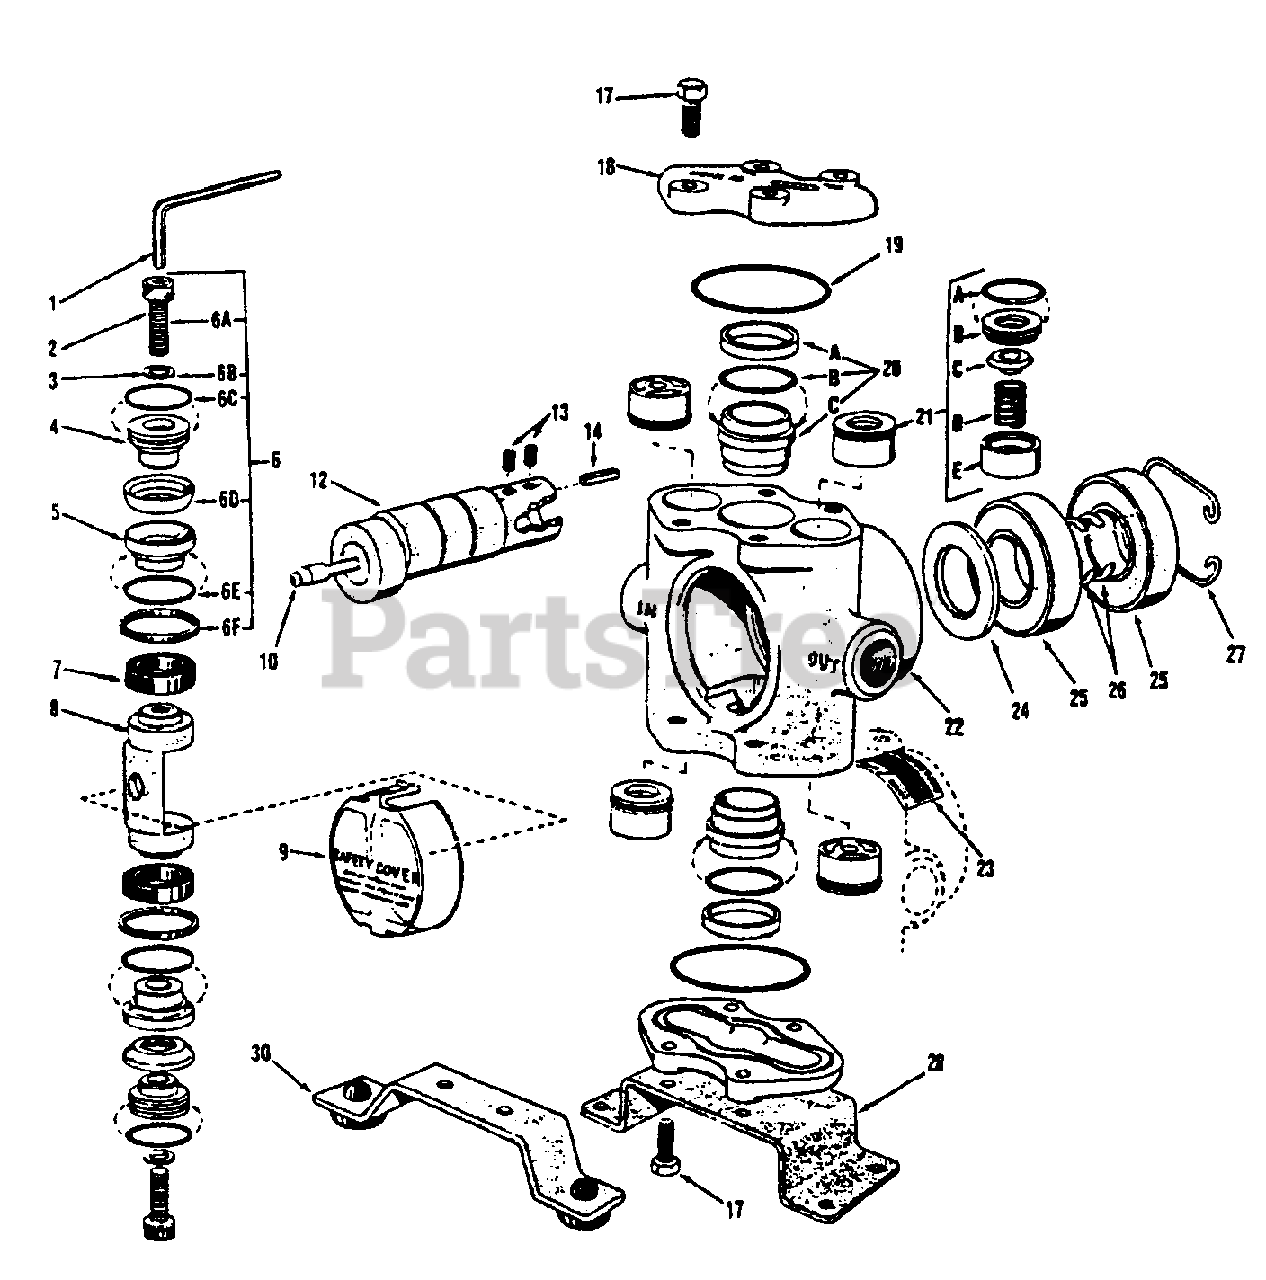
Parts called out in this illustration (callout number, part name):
1	Wrench 3020-0001
2	Piston Cap Screw 2220-0012
3	Washer 2270-0011
4	Piston cap Spreader 1830-0017
5	Cup Backing Plate 1410-0030
6	* Piston Kit Leather Cups 3430-0007
7	Piston Guide 1440-0004
8	Connecting Rod 0502-5300
9	Safety Cover 0608-5300
10	Grease Fitting 2405-0006
12	** Crankshaft Hollow Shaft Pump
13	Set Screw 2230-0017 Hollow Shaft Pump
14	Spline Key 1610-0011 Hollow Shaft Pump
17	Cylinder Head Bolts 2210-0062
18	Cylinder Head 0204-5300C
19	O-Ring Cylinder Head 1720-0038
20	Cylinder Sleeve Assy 3430-0209
20A	Cylinder Sleeve Assy 3550-0019
20B	Cylinder Sleeve Ring 1720-0079
20C	Cylinder Sleeve Assy 3550-0019
21	Unitized Valve Assy 3430-0197
22	Body 0100-5300C
23	Decal 6031-0009
24	Bearing Shield 2130-0007
25	Main Ball Bearing 2008-0001
26	Bearing Ret. Ring (Shaft) 1810-0013
27	Bearing Ret. Ring (Housing) 1820-0025
28	Mounting Base 1510-0020
30	Torque Arm 2820-0028
